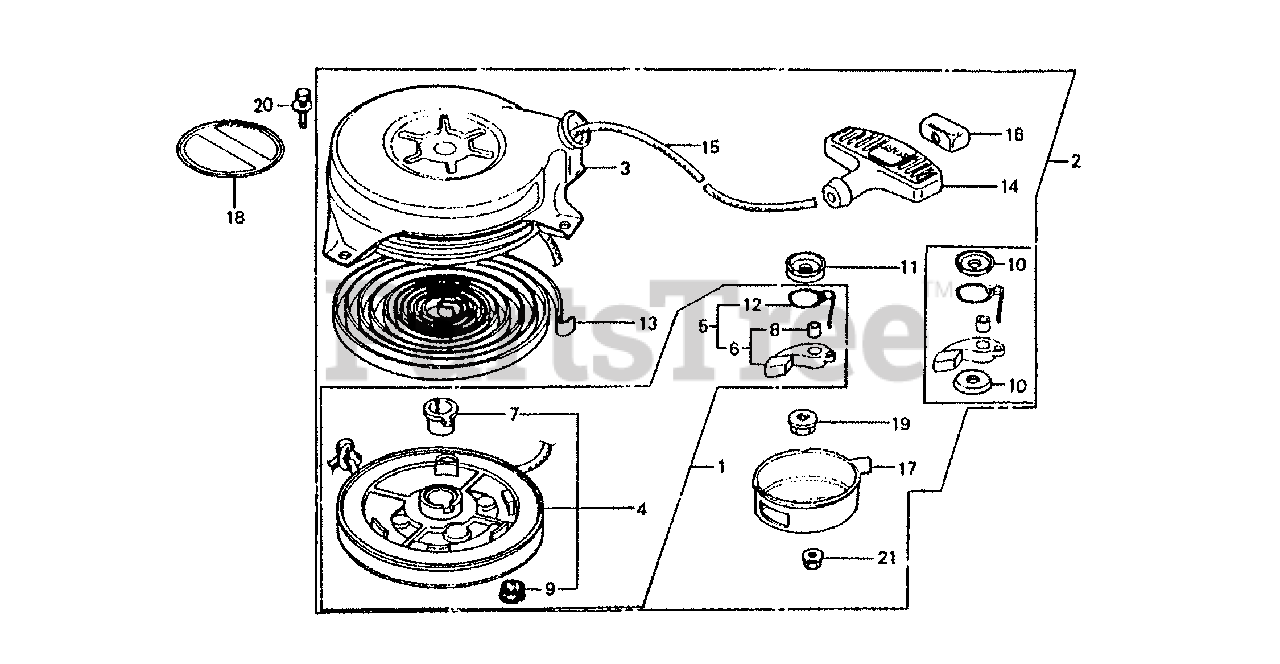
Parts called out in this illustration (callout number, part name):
1	REEL, STARTER
2	STARTER ASSY., RECOIL *NH67* (SPARKLE WHITE)
2	STARTER ASSY., RECOIL *R8* (BRIGHT RED)
3	CASE, STARTER *R8* (BRIGHT RED)
3	CASE, STARTER *NH67* (SPARKLE WHITE)
4	REEL, STARTER
5	RATCHET KIT
6	RATCHET
7	BOSS, REEL
8	BUSH, RATCHET
9	BUSH, REEL STARTER
10	PLATE, FRICTION
11	PLATE, FRICTION
12	SPRING, FRICTION
13	SPRING, RETURN
14	GRIP, STARTER
15	ROPE, STARTER (#5X55")
16	SUPPORT, GRIP
17	COVER, REEL STARTER
18	EMBLEM (HP)
19	NUT, SELF-LOCK (8MM)
20	BOLT, FLANGE (6X8)
21	NUT, FLANGE (5MM)
